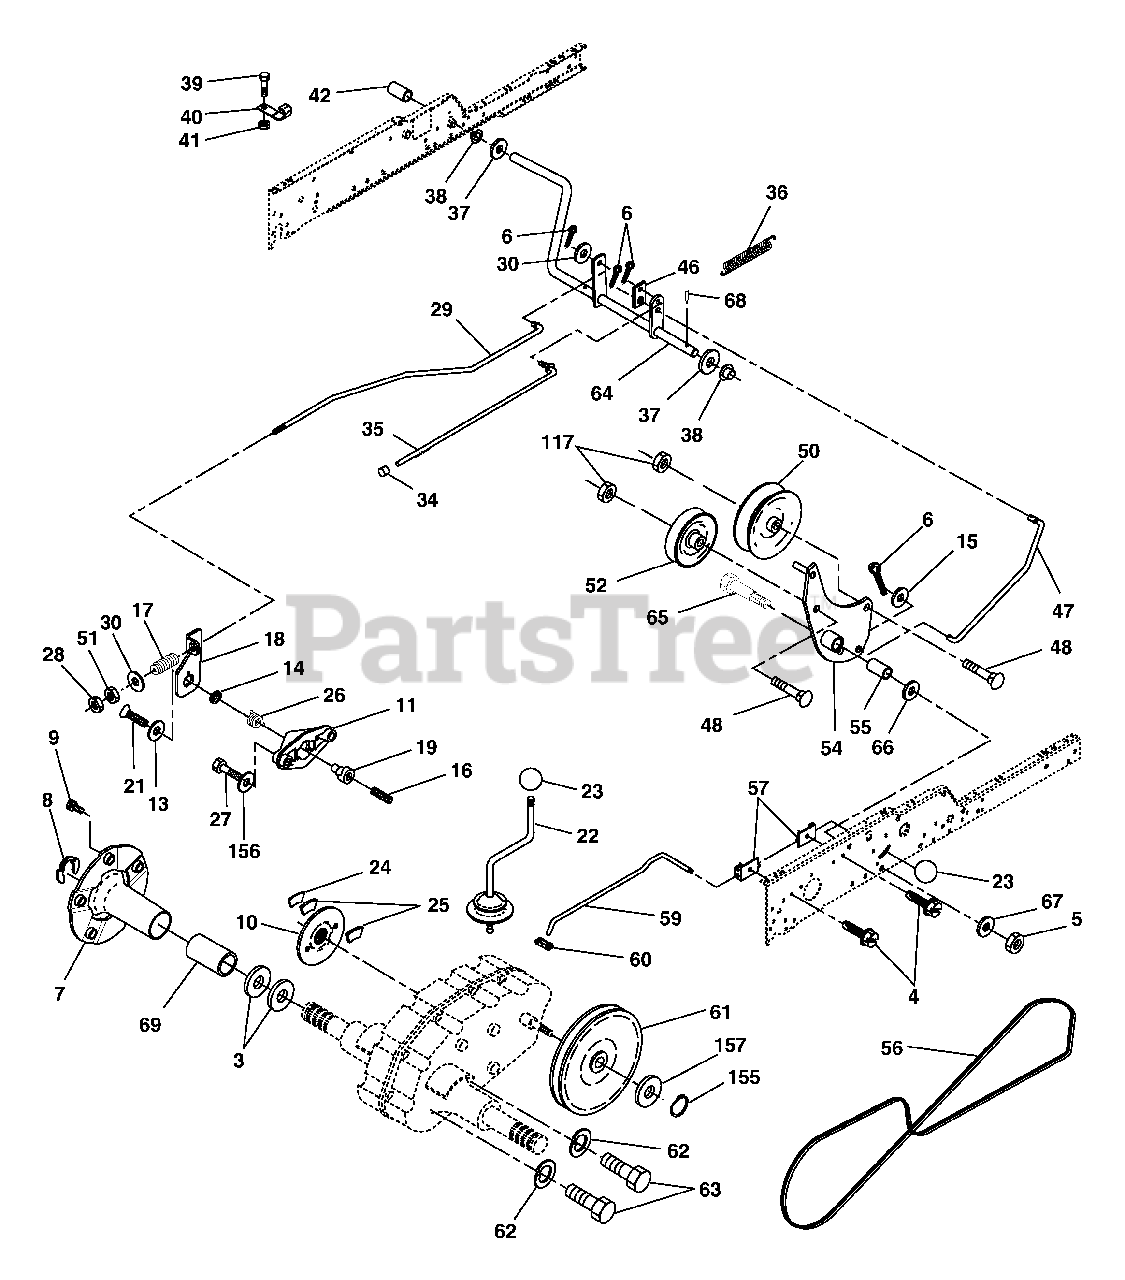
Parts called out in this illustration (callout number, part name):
3	Washer, Thrust, Axle
4	Screw Thdrol 5/16-18 x 3/4
5	Nut, Crownlock 3/8-16
6	Pin, Cotter
7	Wheel, Hub Assembly
8	Klip, Ring
9	Bolt, Hub
10	Disc, Brake
11	Yoke, Brake Disc
13	Washer, Special
14	Bushing
15	Washer 13/32x13/16 x 16 Ga.
16	Set, Screw 1/4-28 x 3/4
17	Spring
18	Lever, Brake
19	Cam, Brake Disc
21	Screw, Flat Head 1/4-28 x 3/4
22	Gearshift, Lever Assembly
23	Knob
24	Support, Puck Brake
25	Puck, Brake Top
26	Spring, Return
27	Bolt Hx Gr 8 5/16-18 UNC x 1-3/4
28	Nut, Hex Jam 3/8-16
29	Brake, Rod
30	Washer 13/32 x 1 x 16 Ga.
34	Cap, Plunger
35	Rod, Parking Brake
36	Spring, Drive Ground
37	Washer 25/32 x 1-1/4 x 16 Ga.
38	Nyliner
39	Screw, Fin. #10-24 x 1
40	Actuator, Interlock Switch
41	Nut, Centerlock #10-24
42	Cover, Pedal
46	Retainer, Spring
47	Clutch Rod
48	Bolt, Carr. 3/8-16 x 1-1/2 Gr. 5
50	Pulley, Idler, Flat
51	Nut, Crownlock 3/8-16 unc
52	Pulley, Idler, Grooved
54	Clutch, Arm Assembly
55	Bearing, Idler
56	V-Belt
57	Bracket, Shift Rod, Hi-Lo
59	Shift Rod, Hi-Lo
60	Spring Clip, Connecting Link
61	Pulley, Transaxle
62	Washer, Lock 7/16
63	Bolt, Fin Hex 7/16-14 x 1-1/4
64	Shaft, Clutch/Brake Pedal
65	Bolt, Shoulder
66	Washer, Hardened
67	Washer, Flat
68	Pin, Roll
69	Hub, Cover
117	Nut, Lock Flg. 3/8-16 unc
155	Ring Retainer
156	Washer Lock Hvy HLCL SPR 5/16
157	Washer Thrust 5/8 x 1.10 x 1/32
